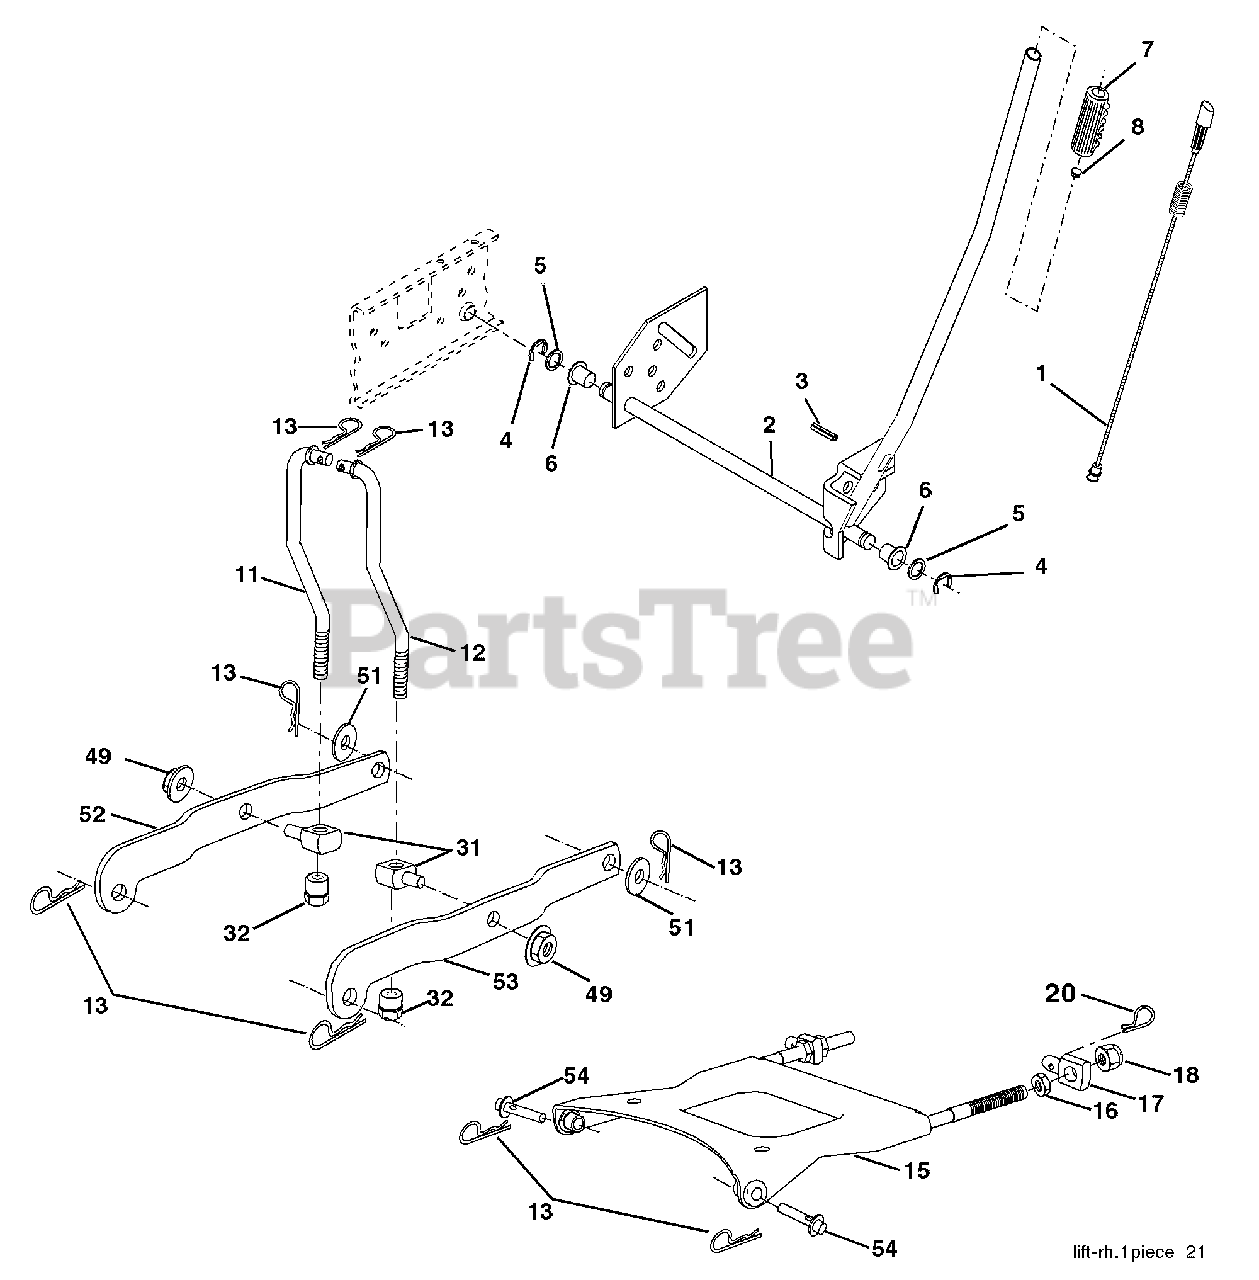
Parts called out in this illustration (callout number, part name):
1	Wire Asm Inner W/plunger 17 32
2	Shaft Asm Lift LH Inf Hgt P/L
3	Pin Groove 1 500 Zinc
4	ERing #5133-62
5	Washer 21/32 x 1 x 21 Ga.
6	Bearing Nylon Blk 629 Id
7	Grip Handle
8	Button Plunger
11	Link Lift LH
12	Link Lift RH
13	Retainer Spring
15	Plate Asm Suspension Front
16	Nut Jam Hex 1/2-13 unc
17	Trunnion Blk Zinc
18	Nut Lock W/wsh 1/2-13 unc
20	Retainer Spring
31	Trunnion Suspension Arm
32	Nut Lift Link 7/16-20
49	Nut Hex Flange Lock
51	Washer 17/32 x 7/8 x 16 Ga.
52	Arm Suspension Rear LH
53	Arm Suspension Rear RH
54	Pin Flange
